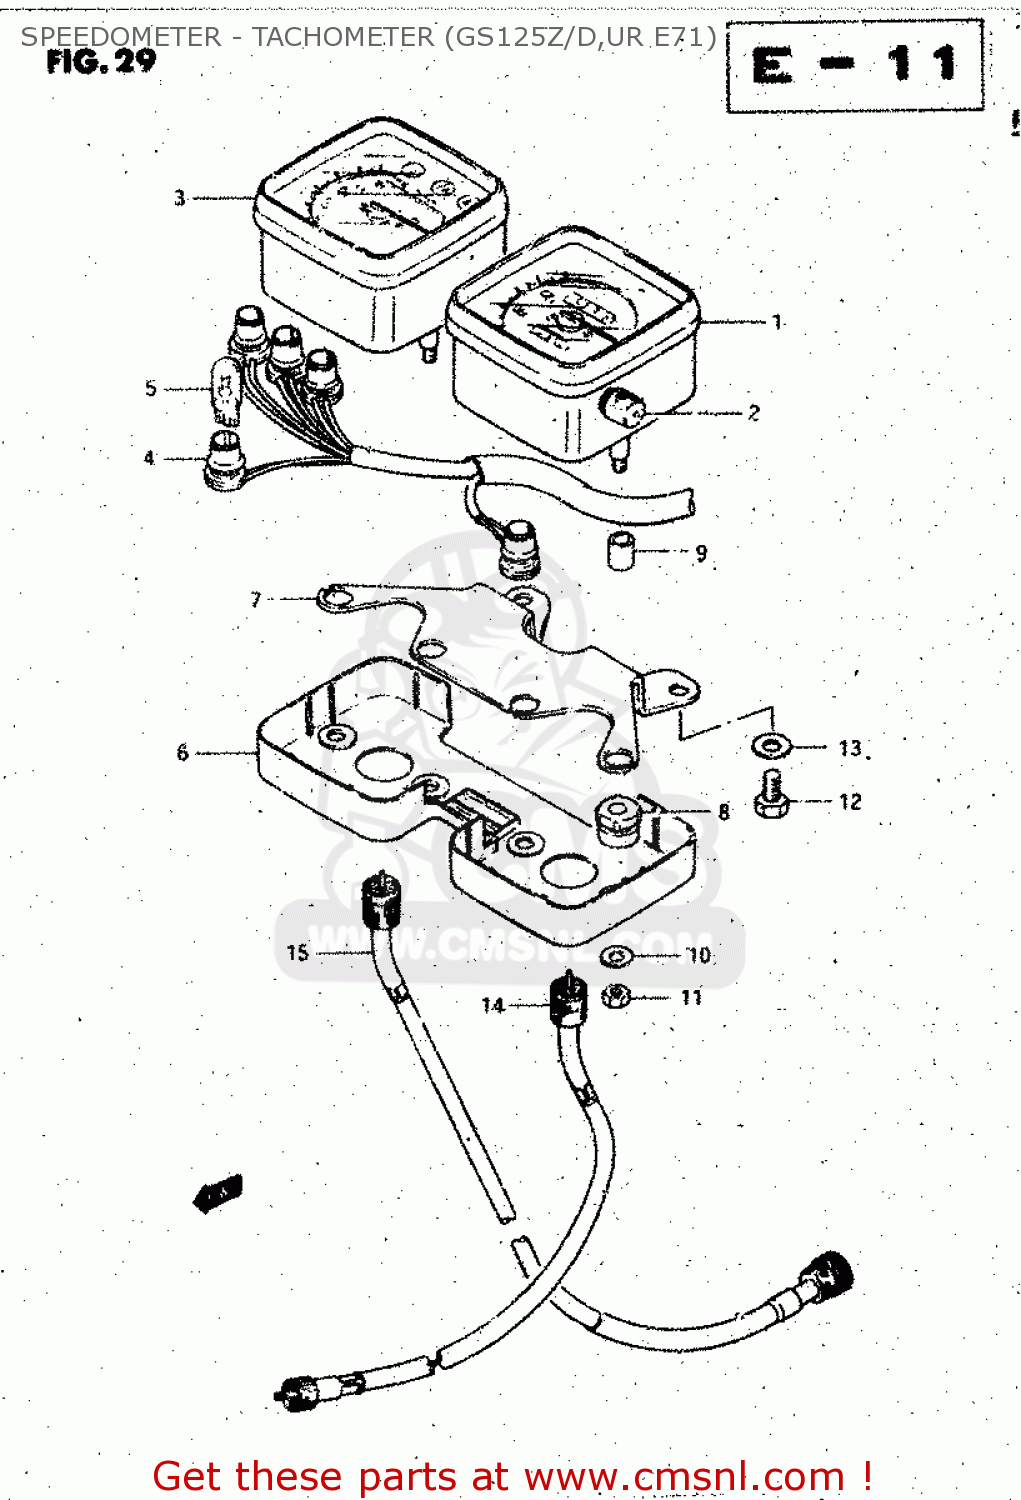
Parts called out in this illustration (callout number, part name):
1	SPEEDOMETER(KILO)
2	KNOB,TRIP
3	TACHOMETER
4	SOCKET
5	BULB(12V3.4W,T10,BF175-01450A)
6	COVER,METER UNDER
7	BRACKET
8	CUSHION,METER
9	SPACER
10	WASHER
11	NUT
12	BOLT
13	WASHER
14	CABLE ASSY,SPEEDOMETER
15	CABLE ASSEMBLY,TACHOMETER
